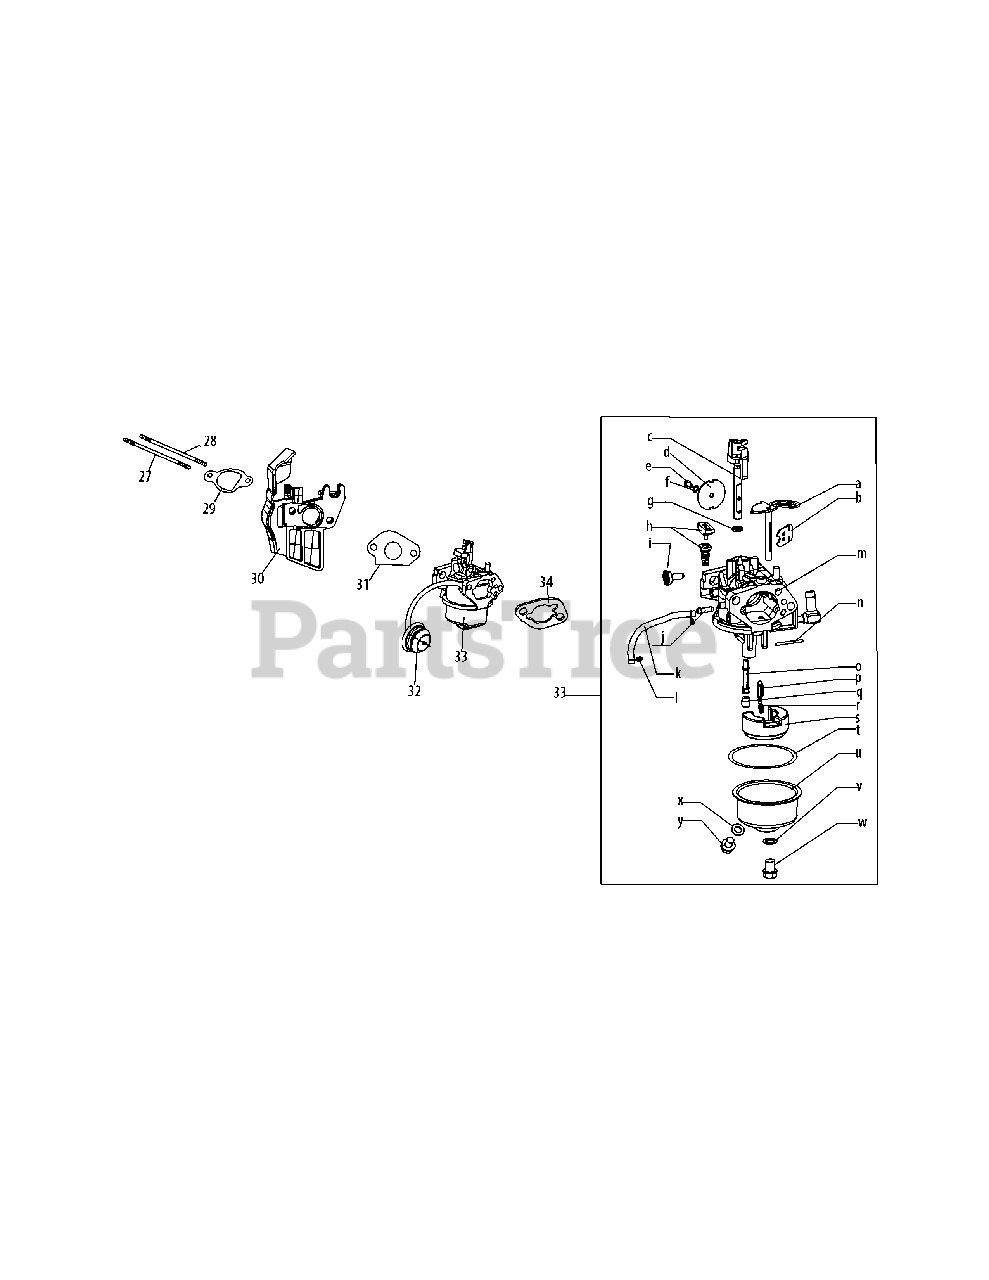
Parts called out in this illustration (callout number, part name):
27	Stud M6×117
28	Stud M6×105
29	Carburetor Insulator Gasket
30	Carburetor Insulator
31	Carburetor Gasket
32	Primer Assembly
32	Primer Bulb
33	Carburetor Assembly
34	Carburetor Gasket Plate
